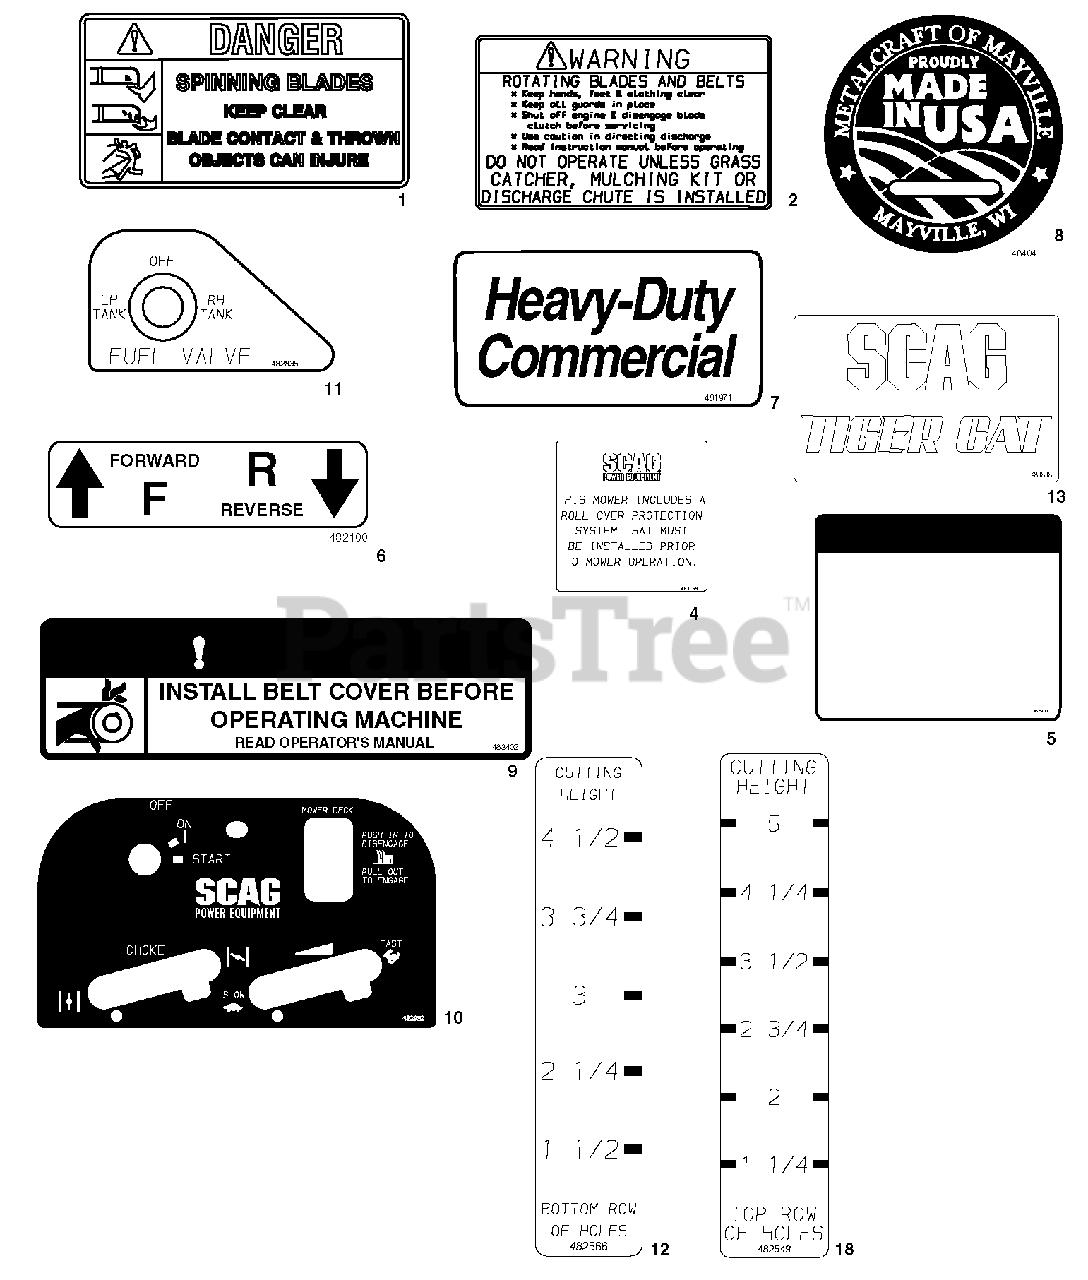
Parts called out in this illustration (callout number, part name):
1	Decal, Danger-Spinning Blades
2	Decal, Warning-Rotating Blades
4	Decal, ROPS
5	Decal, Warning Spark Arrestor (California only)
6	Decal, Traction Control
7	Decal, Heavy Duty Commercial
8	Decal, Metalcraft - Made in USA
9	Decal, Belt Cover
10	Decal, Instrument Panel
10	Decal, Instrument Panel - EFI
11	Decal, Fuel Valve Position
12	Decal, Cutting Height Bottom Row of Holes
13	Decal, Tiger Cat
13	Decal, Tiger Cat EFI
18	Decal, Cutting Height Top Row of Holes
